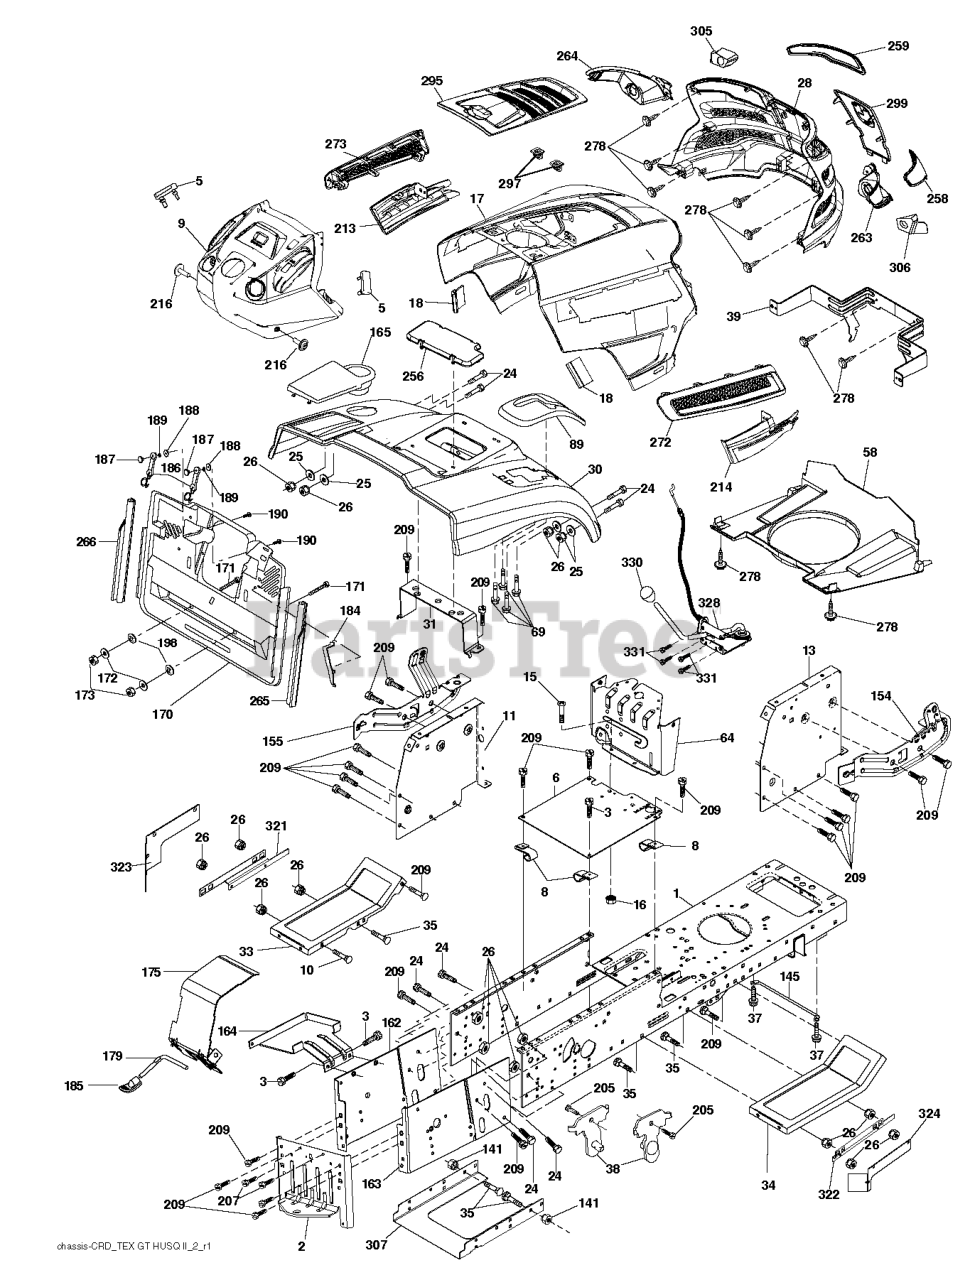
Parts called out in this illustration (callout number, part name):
2	DRAWBAR
3	SCREW 3/8-16X3/4
5	BUMPER DASH
6	PLATE
8	CLIP,INSULATOR
10	BOLT D
11	PANEL DASH LH
13	PANEL DASH RH
16	NUT
17	HOOD.ASM.HUSQVARNA.GT.TEX.ORAN
18	BUMPER.HOOD.TEX.HUSQVARNA
24	BOLT
25	WASHER
26	NUT
28	GRILLE.SUBSTRATE.2011.
30	FENDER.PNT.CRD.MS-668
31	BRACKET SUPPORT FENDER
33	FOOTREST PNT LH
34	FOOTREST PNT RH
35	BOLT
37	SCREW LT
38	BRACKET ASM PIVOT MOWER REAR
39	BRACKET.PIVOT.HOOD.GT.HUSQ.II
58	AIR DUCT.GTV2(1.66"RING HEIGHT
69	SCREW.HI-LO.CONSOLE
89	CONSOLE.CRD.AUTO.GREY.2005
141	NUT LOCK FLG 3/8-16 UNC
145	ROD.PIVOT.HOOD
162	BRACKET
163	BRACKET EXTEN CHASSIS RH CRD
165	COVER.BATTERY.BGGR.ELE
171	BOLT
172	WASHER
175	DOOR TRAP
179	ROD PIVOT FBI
184	BRACKET.ACTUATOR.BAGGER.SRD
186	LATCH ASSY
187	WELDNUT
189	LOCKWASHER #10
190	SCREW
205	SCREW LT
207	SCREW, 5/16-18 X 1/2
209	SCREW, 3/8-16X3/4
213	SIDE.TRIM.LH.GT.HUSQ.II.GRAY
214	SIDE.TRIM.RH.GT.HUSQ.II
216	SCREW 14-20 X 5/8
256	COVER FENDER CRD
258	LENS.HEADLIGHT.RH.GTII.2011
259	LENS.HEADLIGHT.LH.GTII.2011
263	BEZEL LIGHT.RH.GT.II.MYLAR
264	BEZEL LIGHT.LH.GT.II.MYLAR
265	SEALING
266	SEALING
272	VENT.SIDE.RH.GT.HUSQ.II.
273	VENT.SIDE.LH.GT.HUSQ.II.498
278	SCREW.#10 X 0.750.BOS
295	VENT.TOP.EXTERNAL.FILL.GT2.GRE
297	CLIP.RETAINER.TINNER.
299	APPLIQUE.SUBASM.GT.HUSQ.II
305	INSERT.REFLECTIVE.LH.HUSQ.GTII
306	INSERT.REFLECTIVE.RH.HUSQ.GTII
321	SHIELD INNER LEFT
322	SHIELD INNER RIGHT
323	PLATE LEFT
324	PLATE RIGHT
330	RP KNOB.OVAL.TAPERED.3/8-16BLK
331	SCREW.#10-24X5/8.RN.QU
